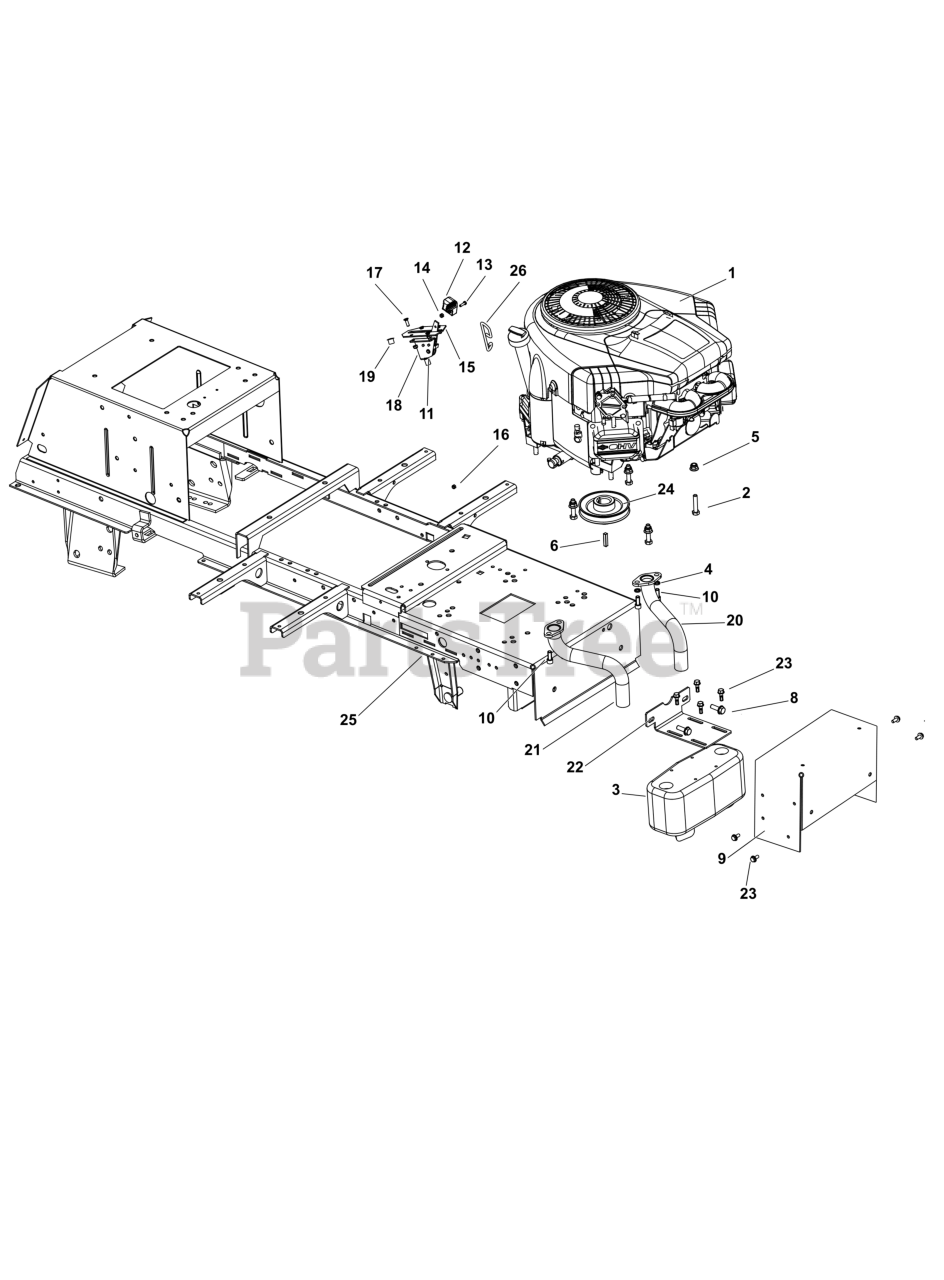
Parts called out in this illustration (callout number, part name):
1	ENGINE, B&S Twin
6	KEY, Drive Pulley
11	LEVER, THROTTLE
12	LEVER, THROTTLE
15	PLATE, Reinforcement
20	MANIFOLD, Exhaust
21	MANIFOLD, Exhaust
